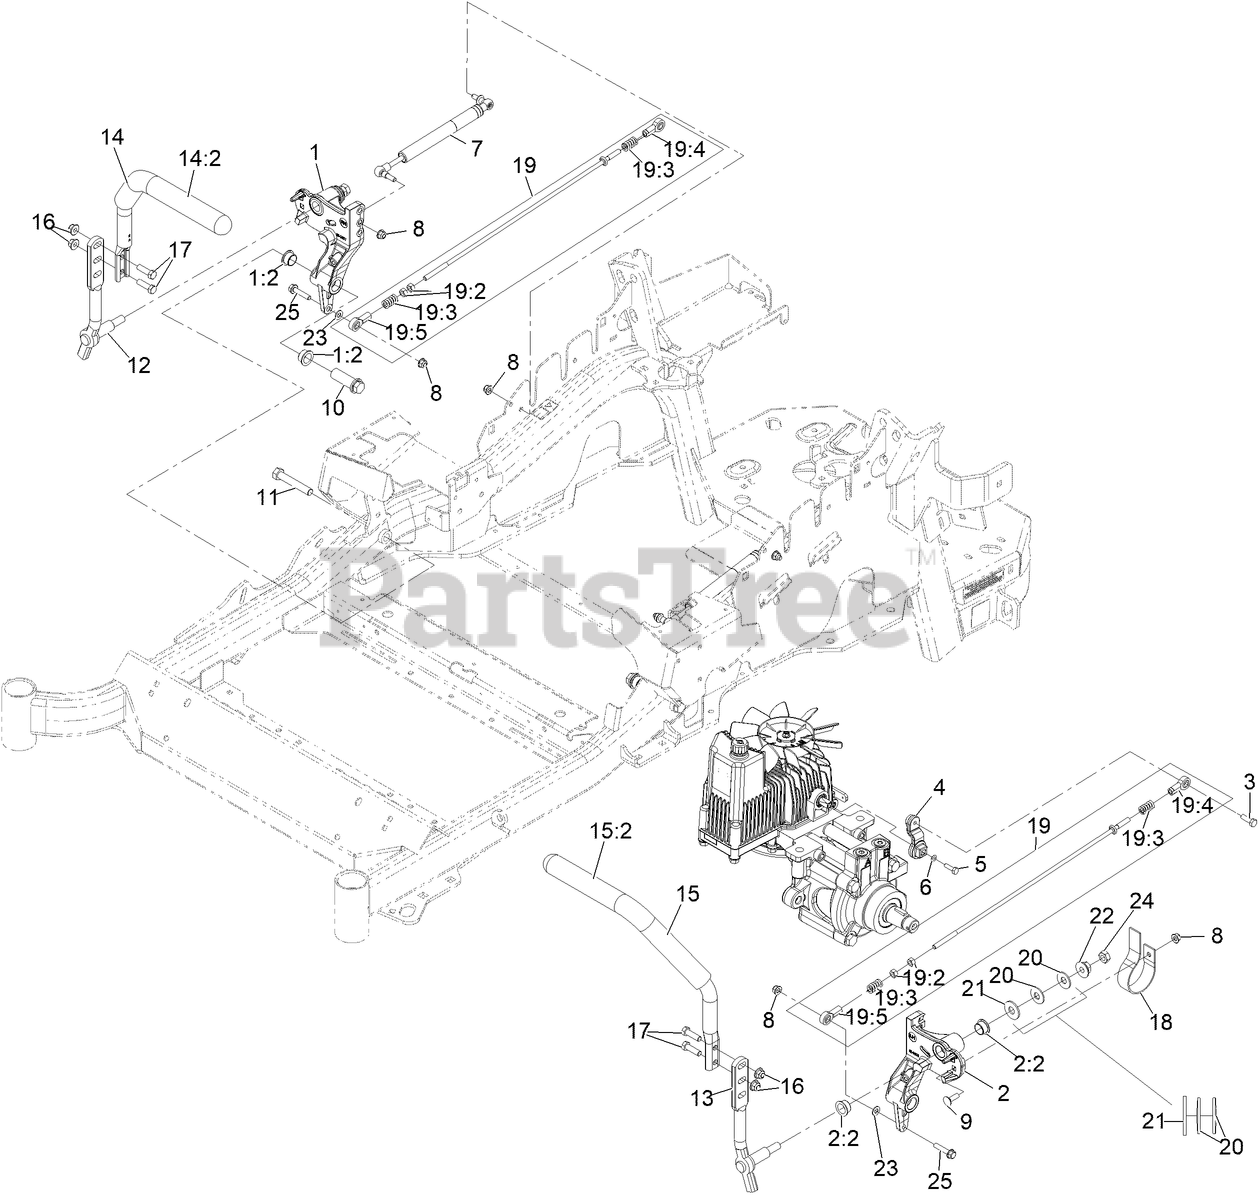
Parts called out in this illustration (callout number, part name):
1	RH MOTION CONTROL AND BUSHING ASM
1:2	BUSHING-FLANGE
2	LH MOTION CONTROL AND BUSHING ASM
2:2	BUSHING-FLANGE
3	SCREW-HH, THREAD LOCKING
4	ARM-CONTROL, PUMP
5	SCREW-HH
6	WASHER-SPRING
7	DAMPER, MOTION CONTROL
8	NUT-HF, NI
9	BOLT-CARR
10	HUB-THREADED
11	SCREW-HH
12	LEVER-CONTROL MOTION, RH
13	LEVER-CONTROL MOTION, LH
14	ASM-HANDLE-RH
14:2	GRIP-CONTROL, LEVER
15	LH HANDLE ASM
15:2	GRIP-CONTROL, LEVER
16	NUT-HF, NI
17	SCREW-HH
18	SPRING-LEAF
19	PUMP LINKAGE REAR ASM
19:2	NUT-HEX
19:3	SPRING-COMPRESSION
19:4	BALLJOINT-LH
19:5	BALLJOINT-RH
20	WASHER-SPRING
21	WASHER-FLAT
22	NUT-HF
23	WASHER-PLAIN
24	NUT-JAM
25	SCREW-HHF
